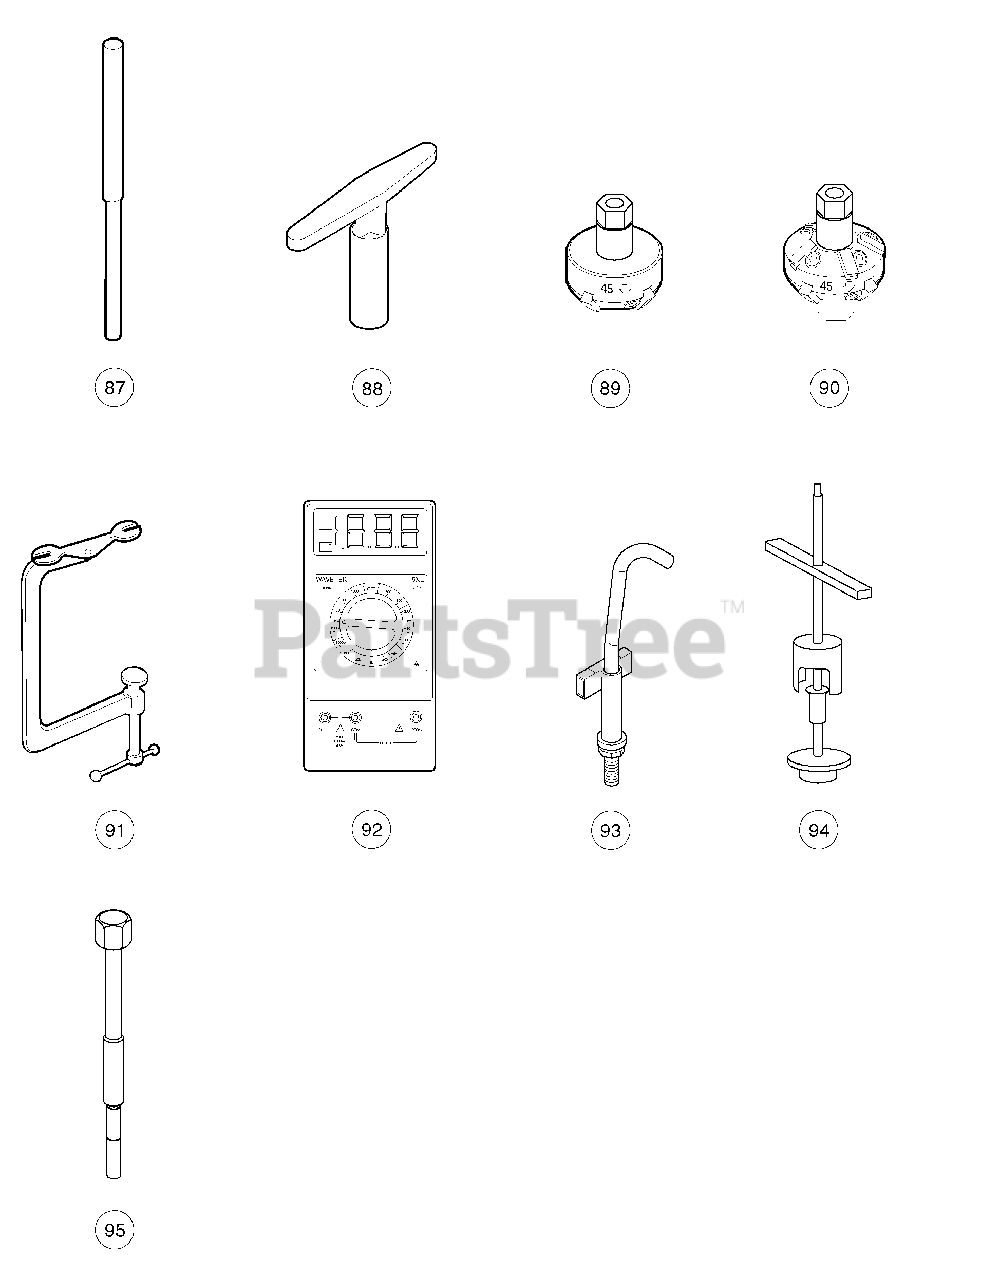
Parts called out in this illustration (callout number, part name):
87	Valve Seat Cutter Guide
88	Valve Seat Cutter T-Wrench
89	Valve Seat Cutter, 45deg (32 mm diameter)
90	Valve Seat Cutter, 45deg/30deg (35 mm diameter)
91	Valve Spring Compressor
92	Volt Ohm Meter
93	Tool, Tensioning, Starter Generator
94	Puller, Drive Clutch, XRT 950
95	Tool, Disassembly, Driven Clutch, XRT 950
